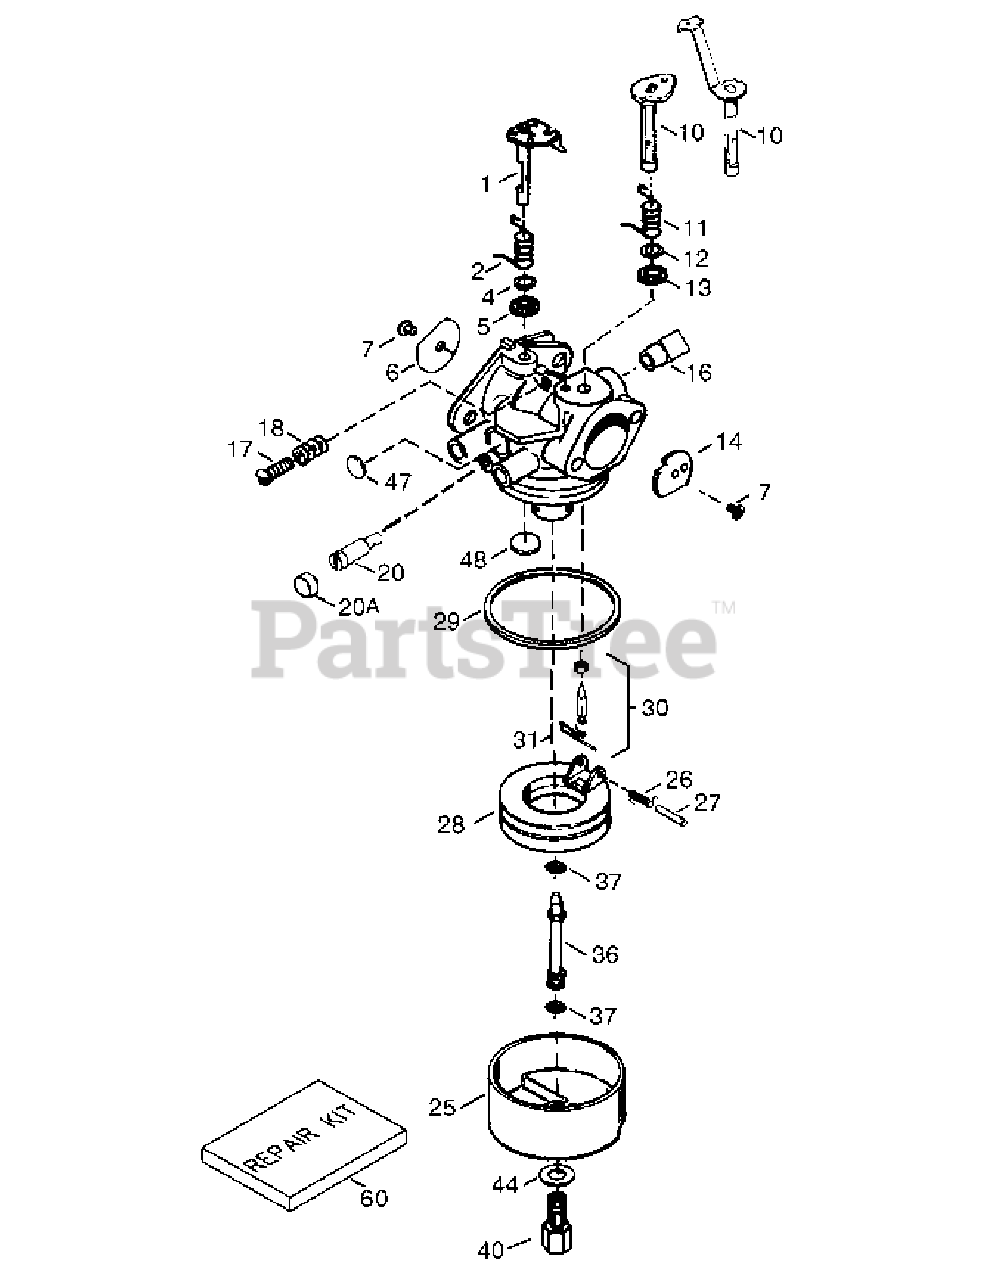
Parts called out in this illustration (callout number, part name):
1	Throttle Shaft & Lever Assembly
2	Throttle Return Spring
6	Throttle Shutter
7	Shutter Screw
10	Choke Shaft & Lever Assembly
14	Choke Shutter
15	Choke Positioning Spring
16	Fuel Fitting
17	Throttle Crack Screw/Idle Speed Screw
18	Tension Spring
20	Idle Restrictor Screw
20A	Idle Restrictor Screw Cap
25	Float Bowl (no drain)
25	Float Bowl Ass'y (Incl. 32 & 33)
27	Float Shaft
28	Float (Plastic)
29	Float Bowl "O" Ring
30	Inlet Needle, Seat & Clip (Incl. 31)
31	Spring Clip
32	Bowl Drain Assembly
33	Drain Plunger Gasket
36	Nozzle Tube
37	"O" Ring, Main Nozzle Tube
40	High Speed Bowl Nut
44	Bowl Nut Washer
47	Welch Plug, Idle Mixture Well
48	Welch Plug, Atmospheric Vent
